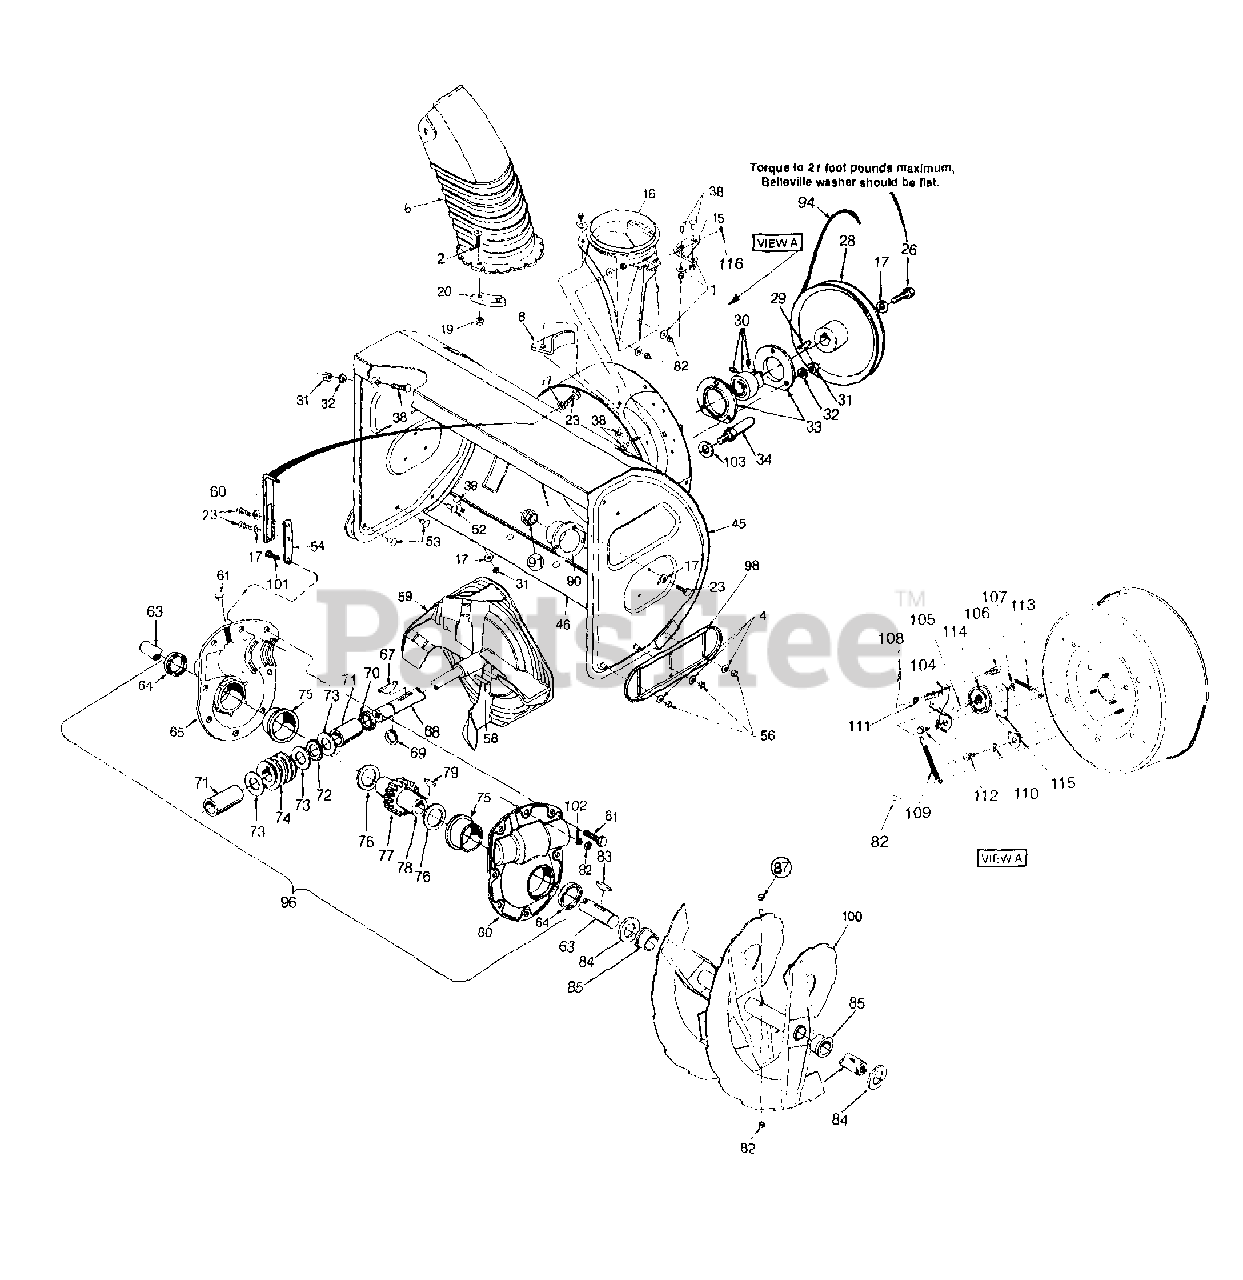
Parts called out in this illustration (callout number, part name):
1	Flat Washer .344 ID x .875 OD
2	Truss. Hd. Mach. Scr. 1/4-20 x .75
4	Belleville washer
6	6" Lower Chute Remote Tilt
16	Chute Adapter
17	Bell. Washer .345 ID x .88 OD x .06
19	Hex Cent. L-Nut 1/4-20 w/ Flange
20	Chute Flange Keeper
23	Hex Wash HD Self-Tap Scr 5/16-18 x .75
26	Hex Screw 5/16-18 x .75
28	1/2" V-Pulley .875 l D x 10.12 OD
29	#9 Hi-Pro Key 3/16 x 3/4 Dia HT
30	Self-Aligning Bearing .875 ID
31	Hex Nut 5/16-18 GD.5
32	L-Wash 5/16 ID
33	Bearing Housing
34	Belt Keeper Studs 3/8-16 x 2.75
38	Carriage Bolt 5/16-18 x .75
52	Carriage Bolt 3/8-16 x 1.00 Gr. 5
53	Carriage Bolt 3/8-16 x .75" Lg.
56	Hex Jam Nut 3/8-16
58	Spring Spiral Pin Heavy 5/16 dia x 1.7
61	Barbed Plug
63	Spiral Axle -33"
64	Oil Seal 1.50 ID Garlock (76 x 6223)
65	Gear Housing Half - RH
67	09 Hi-Pro Key 3/16 x 3/4 dia HT
68	Auger Drive Shaft
69	Snap Ring for .875 dia. shaft
70	Oil Seal for .875 ID (76 x 6133)
71	Sleeve Bearing .875 ID
72	Thrust Bearing .88 ID x 1.44 OD x .078
73	Flat Washer .88 ID x 1.4 OD x .125
74	Worm Gear LH Double Thread
75	Flange Brg. 1.5 ID x 1.75 OD x .80
76	Flat Washer 1.5 ID x 2.0 OD x.03
77	Worm Gear LH Double Thread (Bronze)
78	Worm Gear Shaft
79	#91 Woodruff Key 1/4 x 3/4 dia
80	Gear Housing Half LH
81	Hex Flange Scr. 5/16-18 x .75
82	Hex Ins. L-Nut 5/16-18
83	#91 Woodruff Key 1/4 x 3/4 dia
84	Flat Washer
85	Flange Bearing
87	Shear Bolt 5/16-18 x 1.75
91	Flange Bearing w/flats
94	V-Belt 1/2 x 44 LG
96	Worm Gear Box Ass'y
102	5/16 Sprg Wash
103	3/8 Sprg Lock Wash
104	Brkt Ass'y Brkt
105	Scr Hex Cap 3/8-24 x 1.5 GRD 5
106	Adjustment Ferrule
107	Hex Ins L-Nut 3/8-24
108	Intern Cot-Pin 5/16 dia
109	Spr Extn .470 dia x 4.75 Lg
110	Wave Washer .66 ID x .88 OD
111	Fl-Wash SAE .34 x .68
112	Shld Scr .625 dia x .170 x .062
113	Rod Idler Auger
114	3.0 OD Flat Idler with Flanges
116	Plastic Bushing .380 ID
